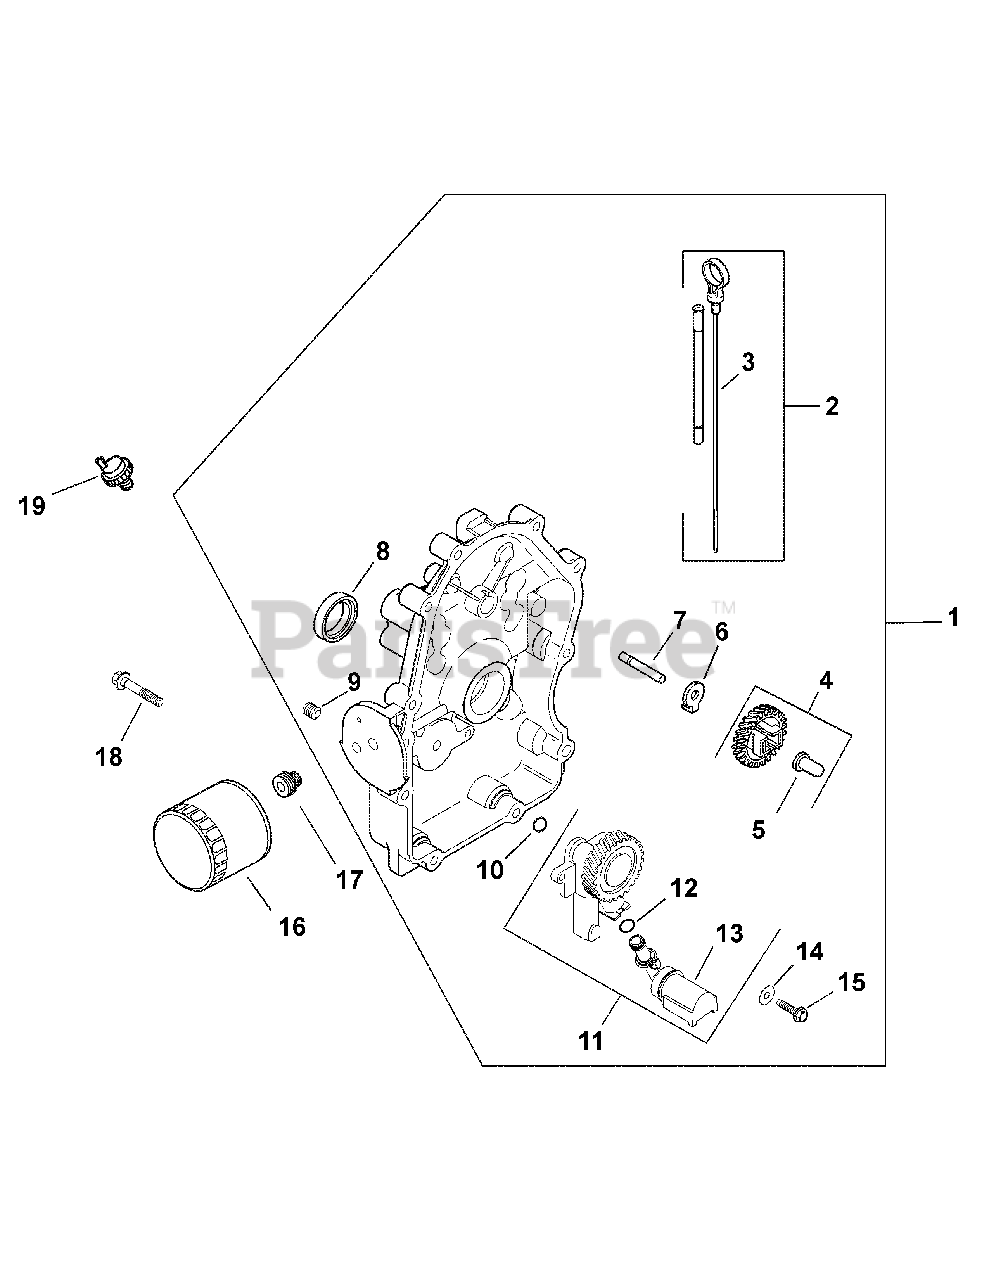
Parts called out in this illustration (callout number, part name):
1	Closure Plate Assembly
2	Kit, Dipstick/ Tubes (Includes 3)
4	Kit, Governor Gear w/Pin (Incl 5)
5	Pin, Governor Regulating
7	Shaft, Governor Gear
9	Plug, Ctsk Pipe, 1/8"
11	Kit, Oil Pump Ass’y (Incl 12, 13)
12	O-Ring, Oil Pick-up
13	Pick-up, Oil
14	Washer, Flat 6 mm
15	Screw, Flg Thd Frm M6x1.0x25
17	Nipple, Oil FIlter
18	Screw, Flg M8 x 1.25 x 45
19	Switch, Oil Pressure
